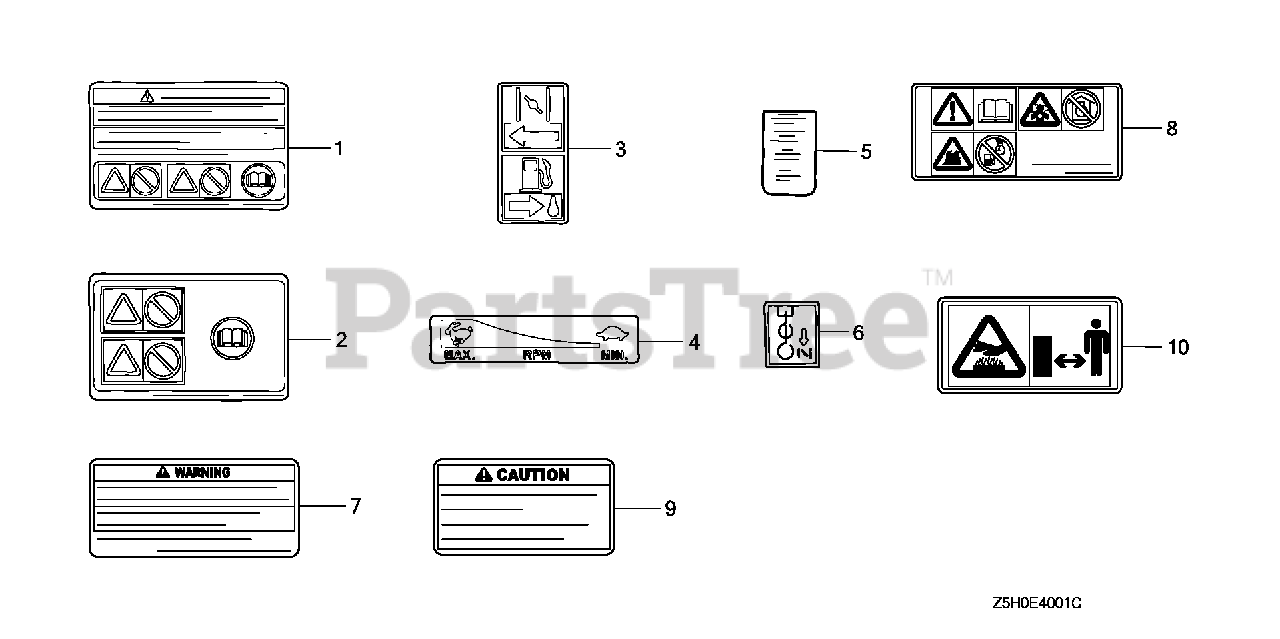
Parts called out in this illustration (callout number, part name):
1	MARK, OPERATOR CAUTION (FRENCH)(MADE IN JAPAN)
7	MARK, OPERATOR CAUTION (FRENCH)(MADE IN JAPAN)
8	MARK, OPERATOR CAUTION (PICTOGRAPH)
9	MARK, EX. CAUTION (FRENCH)
10	MARK, EX. CAUTION (PICTOGRAPH)
